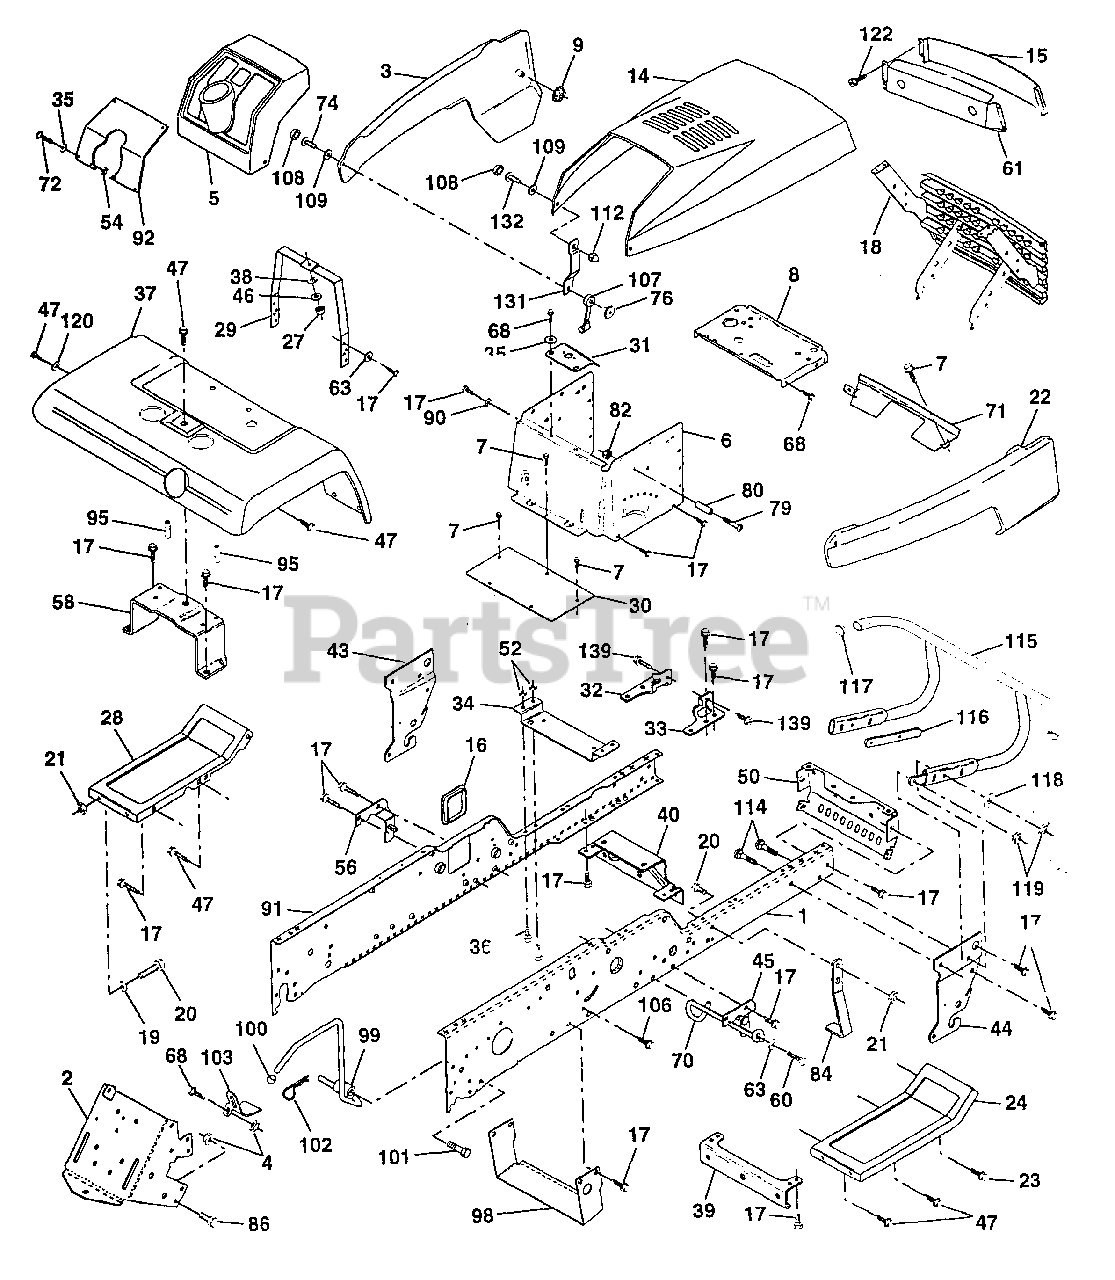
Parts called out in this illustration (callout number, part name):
1	Rail, Frame RH (AYP part number)
2	Drawbar, Gt (AYP part number)
3	Panel Asm., Side LH
4	Nut, Lock Hex 7/16 Unc
5	Dash, Plastic Black
6	Dash, 1PCS, Lower
7	Screw, Thd Cut 1/4-20 x 1/2
8	Support, Battery (AYP part number)
9	Nut, Pal
14	Hood Asm., Pnt
15	Lens, Headlight Bar
16	Cover, Access
17	Screw, Thdrol 3/8-16 x 3/4
18	Grille
19	Washer 13/32 x 13/16 x 12Ga
20	Bolt, Fin Hex 3/8-16 x 1
21	Nut, Crownlock 3/8-16
22	Panel Asm., Side RH (AYP part number)
23	Screw Thdrol 3/8-16 x 1
24	Footrest, RH (AYP part number)
27	Nut, Fin Hex 1/4-20
28	Footrest, LH (AYP part number)
29	Bracket, Support Dash
30	Saddle
31	Bracket Supt 1-pc Vgt Steering
32	Bracket Asm., Frame Pivot Lh
33	Bracket Asm., Frame Pivot Rh
34	Bracket, Engine Support Rear
35	Washer 11/32 x 11/16 x 16 Ga.
36	Bolt, Fin Hex 5/16-18 x 3/4
37	Fender, Pnt.
38	Washer, Lock 1/4
39	Bracket, Axle Front (AYP part number)
40	Bracket, Support Axle/Engine
43	Bracket, Spnsn Front Lh
44	Bracket, Spnsn Front Rh
45	Bracket Asm., Susp Chassis Rh
46	Washer 9/32 x 3/4 x 16 Ga.
47	Screw Thdrol 3/8-16 x 1/2
50	Bracket, Chassis Front
52	Nut, Crownlock 5/16-18
54	Nut 5/16-18
56	Bracket Asm., Susp Chassis Lh
58	Bracket Asm., Fender
60	Screw Thdrol 3/8-16 x 1-1/4
61	Beze. Asem.
63	Washer 13/32 x 1 x 14 Ga. (AYP part number)
68	Screw, Thdrol 5/16-18 x 1/2
70	Guide, Belt Mid Span (AYP part number)
71	Strap, Grille
72	Screw, Mach Trhd 5/16-18 x 3/4
74	Screw, Machine #10-24
76	Nut, Weld #10-24
79	Screw, Machine #10-24 x 1/4
80	Spacer, Split
82	Nut #10-24
84	Stop, Over Center Mower
86	Bolt, Fin Hex 7/16-14 Unc x 1 (AYP part number)
90	Washer, Lock External Tooth 3/8
91	Rail, Frame Lh (AYP part number)
92	Plate, Silkscreen Dash
95	Push Nut, Nylon
98	Bracket Chassis Skid (AYP part number)
99	Rod Asm. Bypass
100	Cap Brake Parking Red
101	Screw Thdrol. 3/8-16 x 1-3/4
102	Retainer Spring 1"
103	Bracket Lock Bypass
106	Screw Thdrol Hex Head Zinc (AYP part number)
107	Latch, Chute Blk
108	Cap, Snap Black
109	Cap, Washer Snap Nat
112	Nut, Acorn, Hex #10-24
114	Bolt, Carriage 3/8-16 x 1-1/4
115	Bumper Asm.
116	Bracket Extension Bumper (AYP part number)
117	Plug, Plastic
118	Washer 13/32 x 13/16 x 16 Ga.
119	Nut, Crownlock 3/8-16 UNC
120	Washer 13/32 x 1 x 16 Ga.
122	Screw Hex Wshd 8-18 x 7/8
131	Bracket Support Hood/Panel YP
132	Screw Truss Hd #10-24 x 3/8
139	Bolt Shoulder 5/16-18 TT
